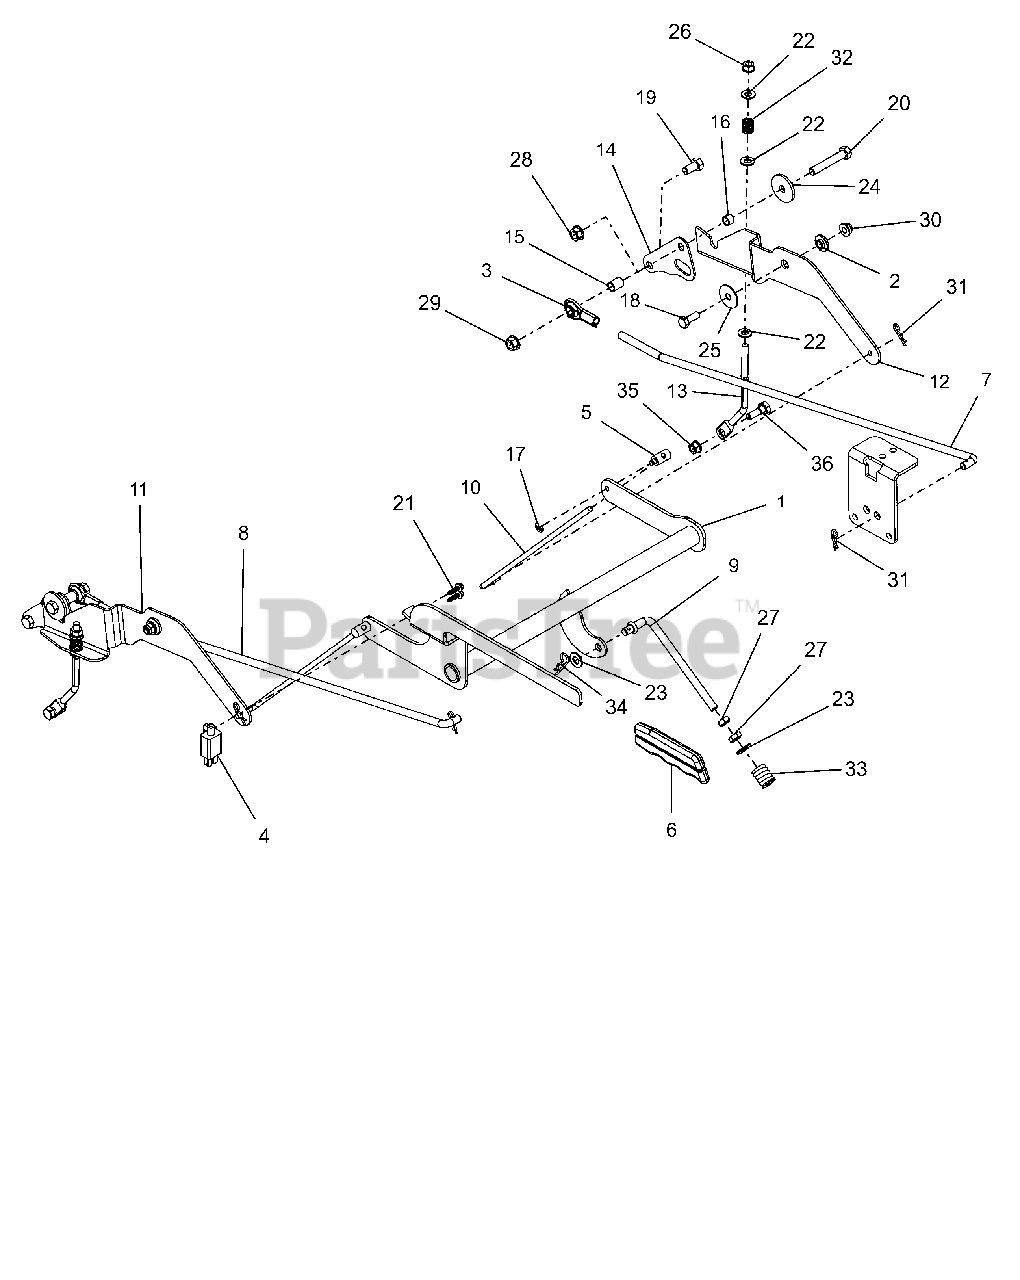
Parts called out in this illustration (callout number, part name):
1	WLDMT, BRAKE LEVER
2	BSHG, FLG .325X.499X.26X.88
3	ROD END, .38 RH
4	SWITCH- DOUBLE POLE N.O./N.O.
5	TRUNION, 1/4-20
6	GRIP, PARKING BRAKE (YELLOW)
7	STEERING, LINKAGE LH
8	STEERING, LINKAGE RH
9	LINK, OVER CENTER, PARKING BRK
10	ROD, PARK BRAKE
11	INTERLOCK, RH BRAKE LINK
12	INTERLOCK, LH BRAKE LINK
13	LINK, BRAKE (XL)
14	PLATE, TRANSAXLE ADAPTOR
15	SPCR, SLV .385X.500X.652
16	SPCR, SLV .385X.500X.350
17	RG-RTNG-EXT .250X.025
18	BLT, HEX .31-18X.875 G5 ZCC
19	BLT,HEX .38-16X.75 G5 ZCC
20	BLT,HEX .38-16X2.25 G5 ZCC
21	SCR, PLASTITE-HWH 0.2 X 0.75 ZC120
22	WSHR,FLT .344X.688X.065 ZCC
23	WSHR,FLT .406X.812X.065 ZCC
24	WSHR, FLT .380X1.50X.125 ZCC
25	WSHR, FLT .347X1.254X.048 ZCC
26	NUT,LK-CTR-FLG .31-18 GF ZCC
27	NUT-JAM .375-16 G2 ZCC
28	NUT-LK-TOP-FLG .38-16 ZC120
29	NUT-LK-CTR-FLG .375-16 GF ZCC
30	NUT,NYL-FLG .31-18 GF ZCC
31	PIN, HAIR #213 .08X1.19 ZCC
32	SPRING, COMPRESSION
33	SG-COMP .187X.56X1.62
34	PIN-HAIR CTR .09 X 1.50 YWZC
35	NUT-LK-TOP-FLG .312-18 GF ZCC
36	BOLT,SHLDR .38X.25 -.31-18X.75
